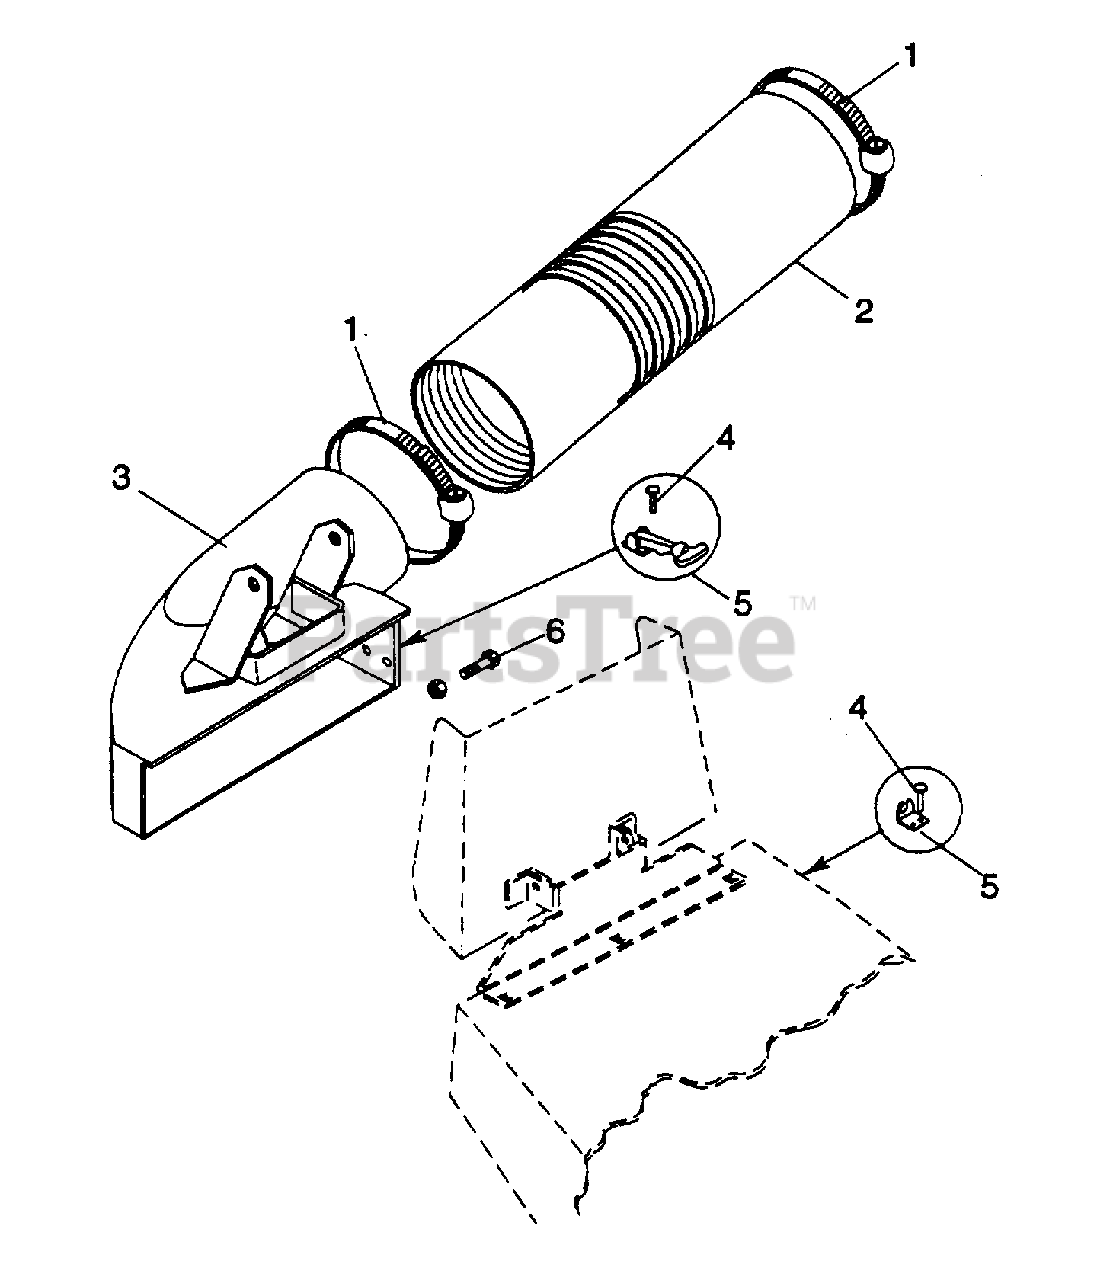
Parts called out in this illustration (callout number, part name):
1	Clamp
2	Hose, Mower to Blower
3	60" Boot w/Decal
4	Rivet, Dome Head
5	Latch, Flexible Draw
6	Bolt, Hex 3/8-16x1.50
